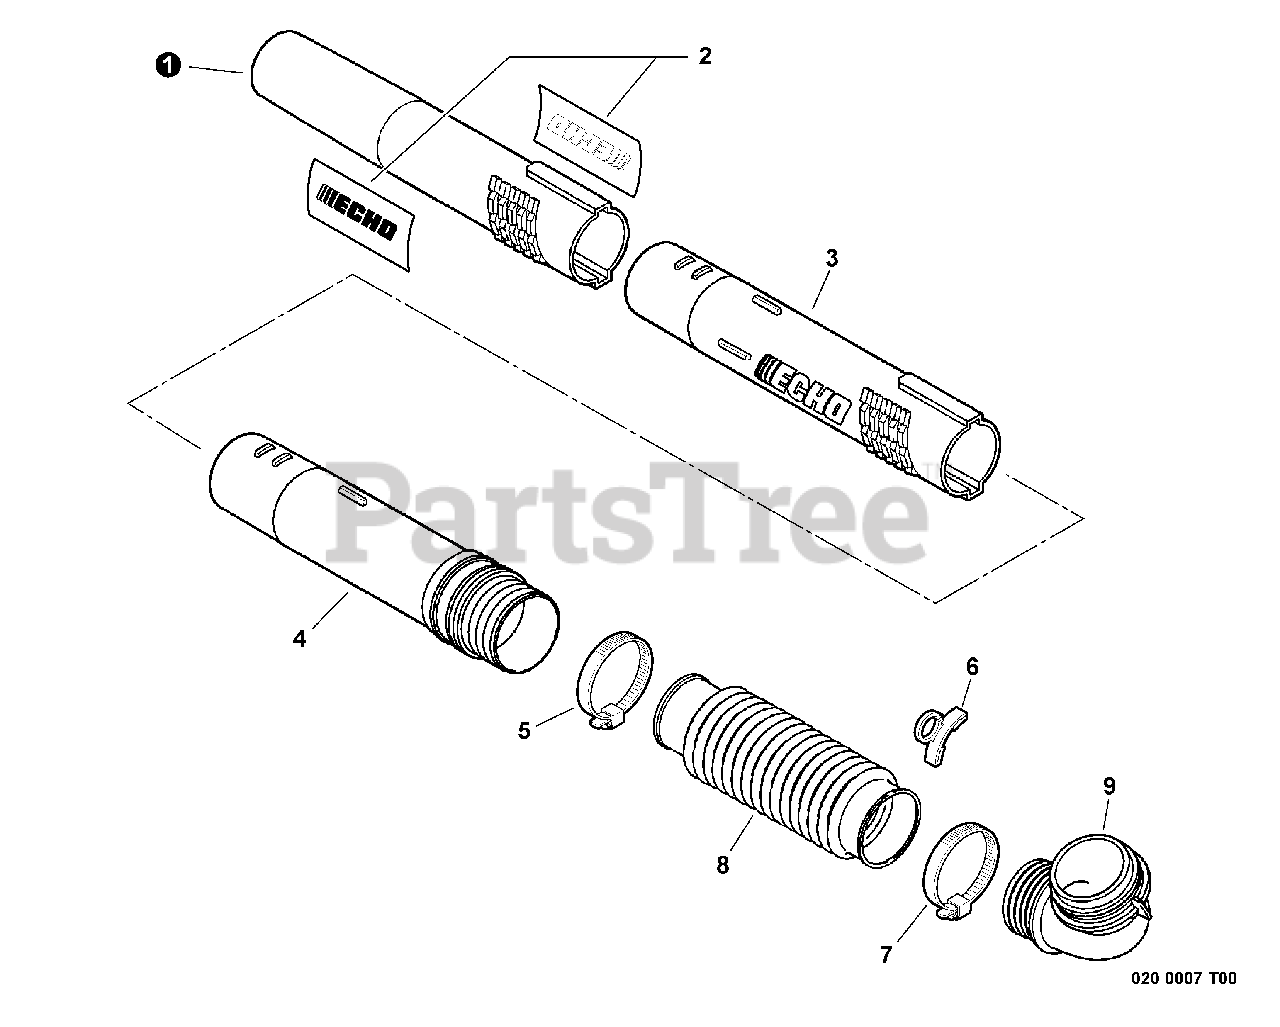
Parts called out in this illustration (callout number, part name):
1	TUBE, BLOWER - NOZZLE
2	LABEL - ECHO
3	TUBE, BLOWER - STRAIGHT
4	TUBE, BLOWER - SWIVEL
5	CLAMP, HOSE
6	CLIP, CABLE
7	CLAMP, HOSE
8	TUBE, BLOWER - FLEXIBLE
9	TUBE, BLOWER - ELBOW
